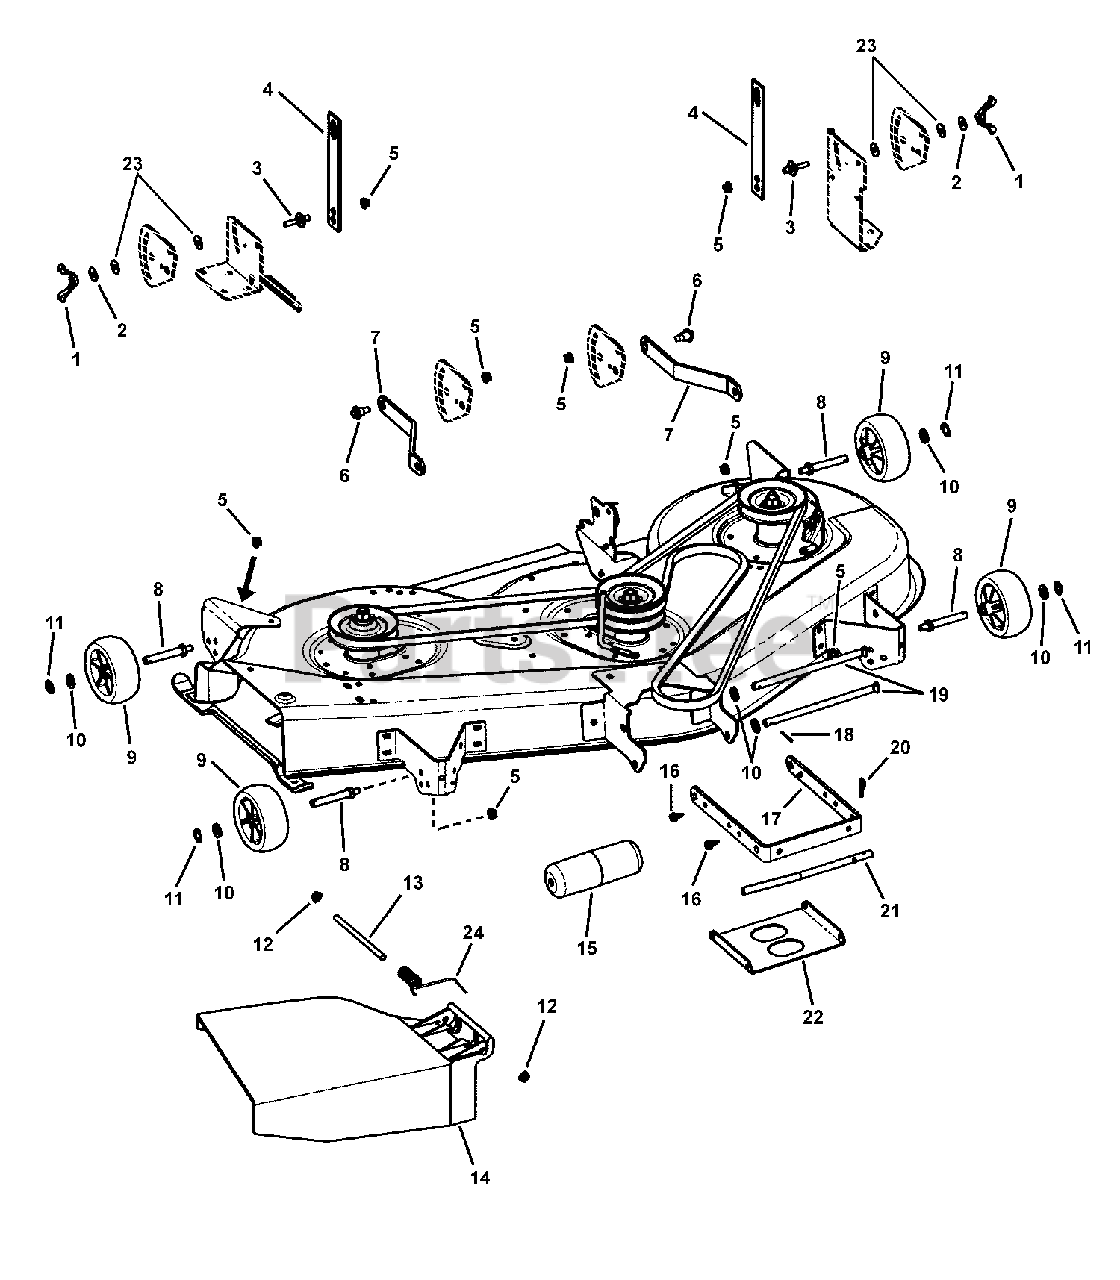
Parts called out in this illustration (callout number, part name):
1	WINGNUT (5/16-18 thread)
2	WASHER, Flat, 1.0 x .328 x 16 GA
3	PIN, Hanger 3/8-16 x 1-1/4"
4	LINK, Lift
5	NUT, 3/8-16 Hex Flange Lock, NC
6	SHOULDER BOLT, 3/8-16 x .600 OD x .95 L
7	BRACKET, Rear Suspension
8	BOLT, Axle, 3/8-16 x 3"
9	WHEEL, Gage
10	WASHER, Flat, 1.0OD x 0.550"
11	CLIP, Hair Pin
12	CAP, Push On (for .375 dia. Stud)
13	ROD, Deflector
14	DEFLECTOR, Chute
15	ROLLER
16	SCREW, 5/16-18 Hex Washer Self-Tap
17	BRACKET, Suspension, Front
18	COTTER PIN, 1/8 x 1-1/4"
19	ROD, Deck Suspension
20	HAIR PIN, .092 Dia.
21	ROD, Hanger
22	STIFFENER
23	NUT, 5/16-18 Hex Flange Lock, NC
24	SPRING, Torsion
